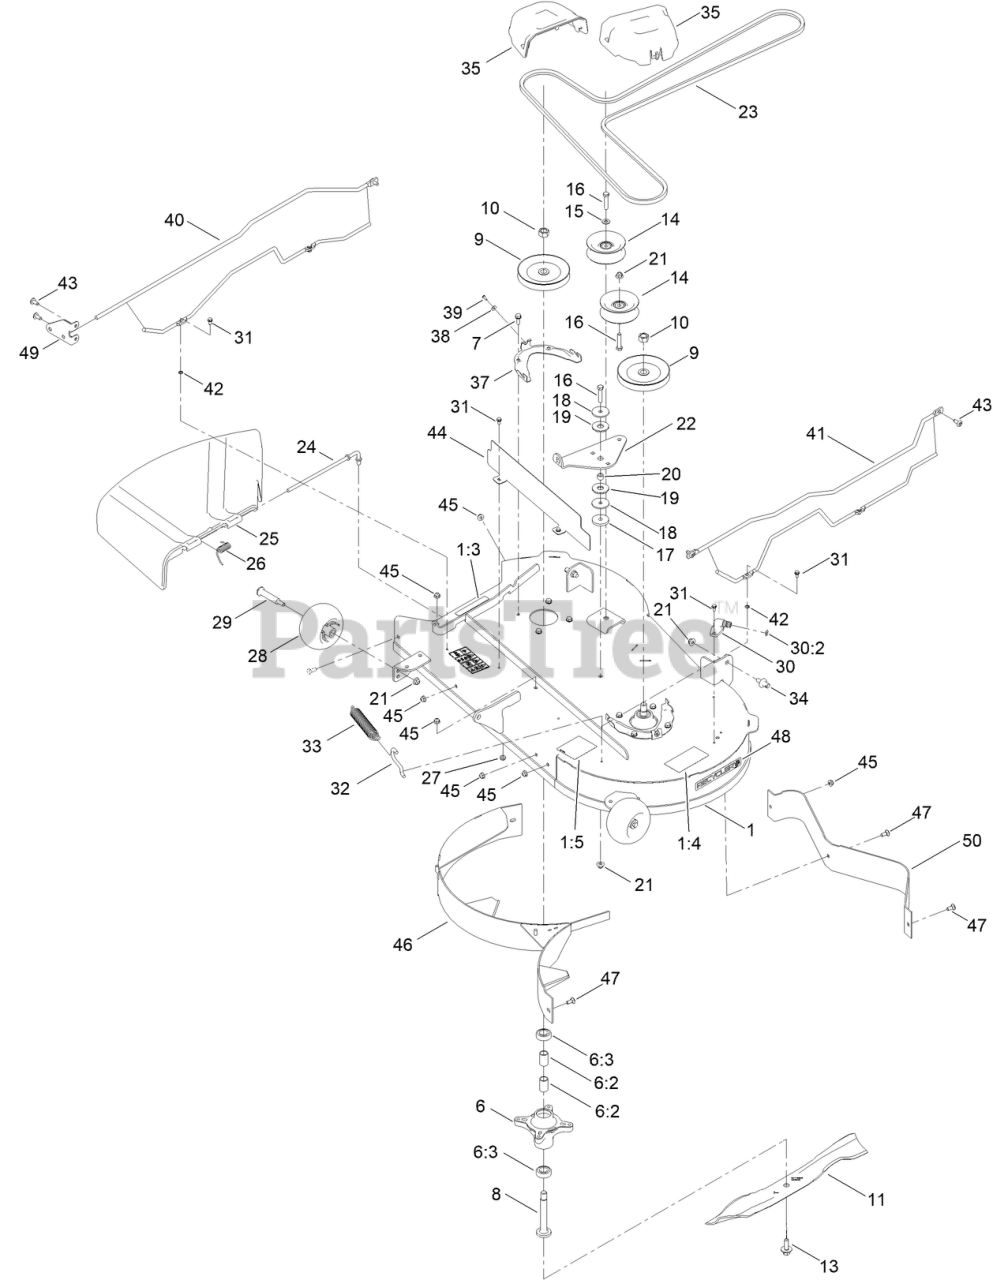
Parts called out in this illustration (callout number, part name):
1	42IN DECK AND DECAL ASM
1:3	DECAL-DANGER
1:4	DECAL-DANGER, DECK
1:5	DECAL-ROUTING, BELT
6	SPINDLE ASM
6:2	SPACER
6:3	BEARING-BALL
7	SCREW-TAPTITE
8	SHAFT-SPINDLE
9	Pulley
10	Nut-Hex
11	BLADE-MULCH
13	BOLT-BLADE, SEMS
14	PULLEY-IDLER, FLAT
15	WASHER-FLAT
16	SCREW-HH
17	WASHER-PLAIN
18	Washer
19	WASHER-FRICTION, COMPOSITE
20	SPACER
21	NUT-HF, NI
22	ARM-IDLER
23	V-BELT
24	ROD-PIVOT
25	DEFLECTOR-DISCHARGE
26	SPRING-TORSION
27	NUT-HEX
28	ROLLER-SCALP, ANTI
29	BOLT-SHOULDER
30	FITTING-WASHOUT
30:2	O-RING
31	SCREW-HWH
32	HOOK-RETURN SPRING
33	SPRING-EXTENSION
34	PIN-DECK
35	COVER-BELT
37	BRACKET-COVER, BELT
38	WASHER-PLAIN
39	SCREW
40	LEFT GUARD ASM
41	RIGHT GUARD ASM
42	NUT-RETAINING
44	SHIELD-FROUNT
45	NUT-HF
46	BAFFLE-RECYCLING
47	BOLT-CARR
48	DECAL-RECYCLER
49	PLATE-MOUNT, GUARD
50	DEFLECTOR
